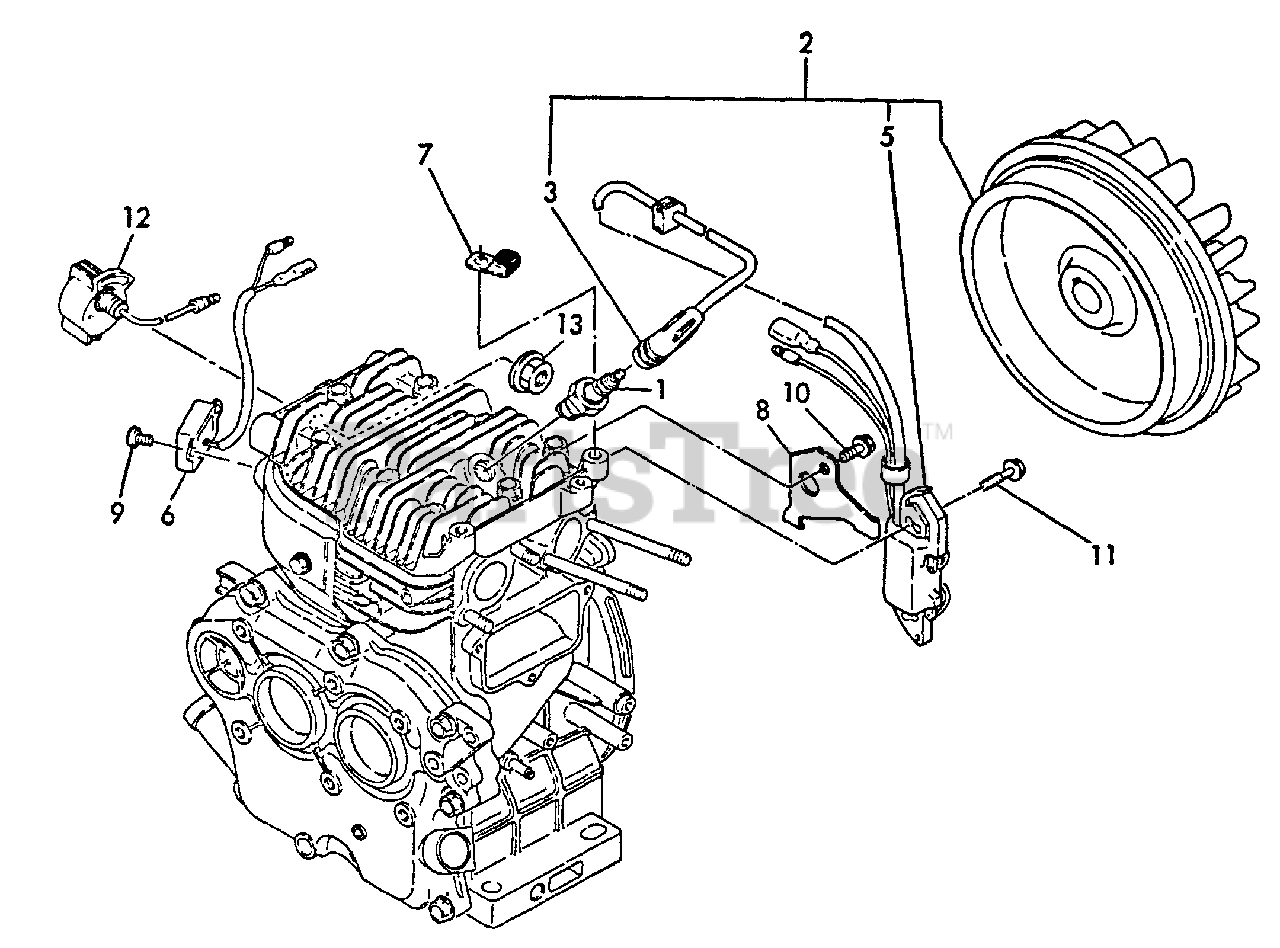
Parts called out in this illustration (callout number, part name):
1	SPARK PLUG
2	FLYWHEEL W/MAGNET
3	CAP, PLUG
5	COIL, IGNITION
6	IGNITER
7	CLAMP
8	CLAMP
9	SCREW - 5X10
10	BOLT - 6X8 -- PLATED
11	BOLT - 6X25
12	IGNITION SWITCH ASSY
13	NUT - 8
